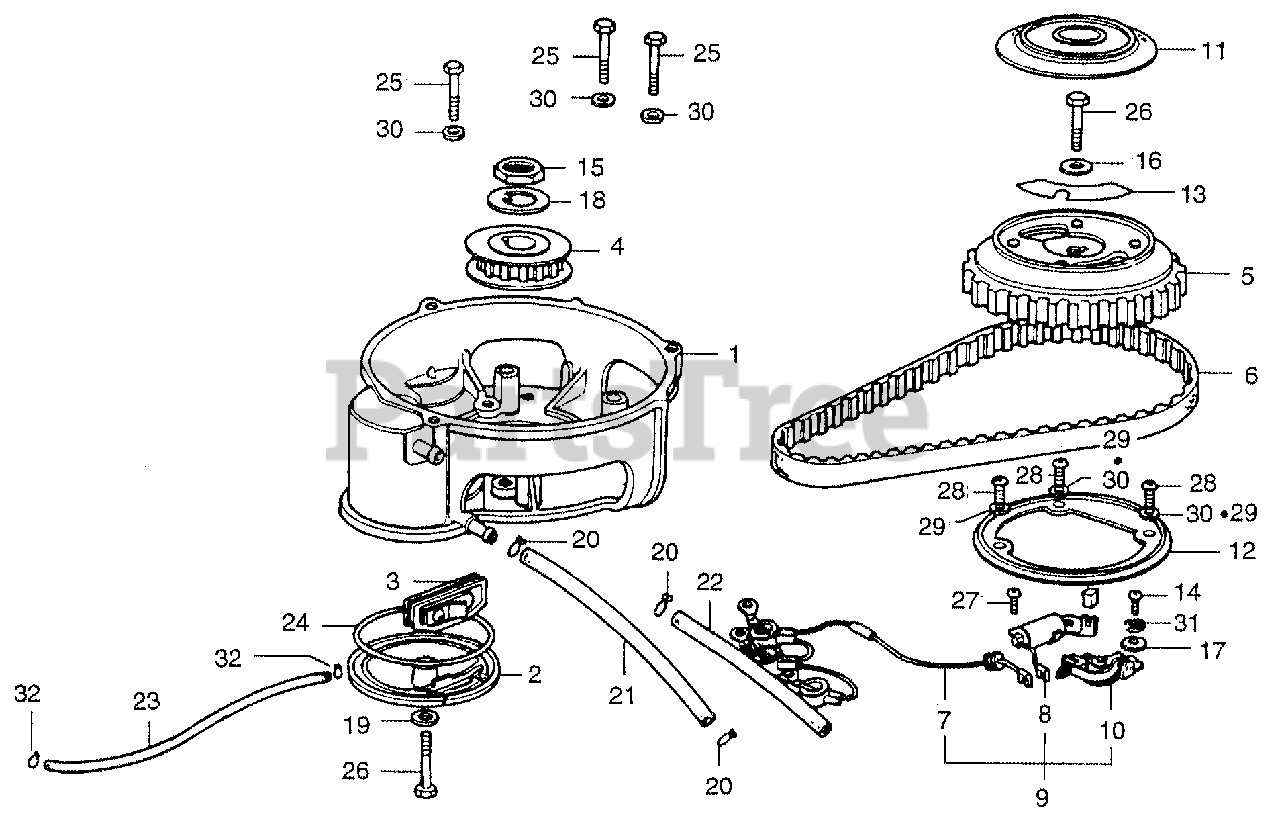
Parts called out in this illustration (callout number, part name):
1	CASE, STARTER (NOT AVAILABLE)
2	CAP, BREATHER
3	BODY, VALVE
4	PULLEY, TIMING
5	PULLEY, CAM (NOT AVAILABLE)
6	BELT, TIMING
7	WIRE, BREAKER (NOT AVAILABLE)
8	CONDENSER
9	POINTS ASSY. (TOYO) (NOT AVAILABLE)
10	POINTS
11	COVER, POINT
12	CASE, ADVANCER (NOT AVAILABLE)
13	MARK, POINT
14	SCREW, PAN (5X10) (NOT AVAILABLE)
15	NUT, LOCK (22MM)
16	WASHER (6MM) (NOT AVAILABLE)
17	WASHER, BREAKER SETTING
18	WASHER, LOCK (22MM) (NOT AVAILABLE)
19	WASHER A (6MM)
20	CLIP, TUBE (C11) (NOT AVAILABLE)
21	TUBE A, BREATHER (NOT AVAILABLE)
22	TUBE B, BREATHER
23	TUBE, OIL RETURN
24	O-RING (67MM)
25	BOLT, HEX. (6X25)
26	BOLT, HEX. (6X28)
27	SCREW, PAN (5X8)
28	SCREW, PAN (5X12)
29	WASHER, PLAIN (5MM)
30	WASHER, PLAIN (6MM)
31	WASHER, SPRING (5MM)
